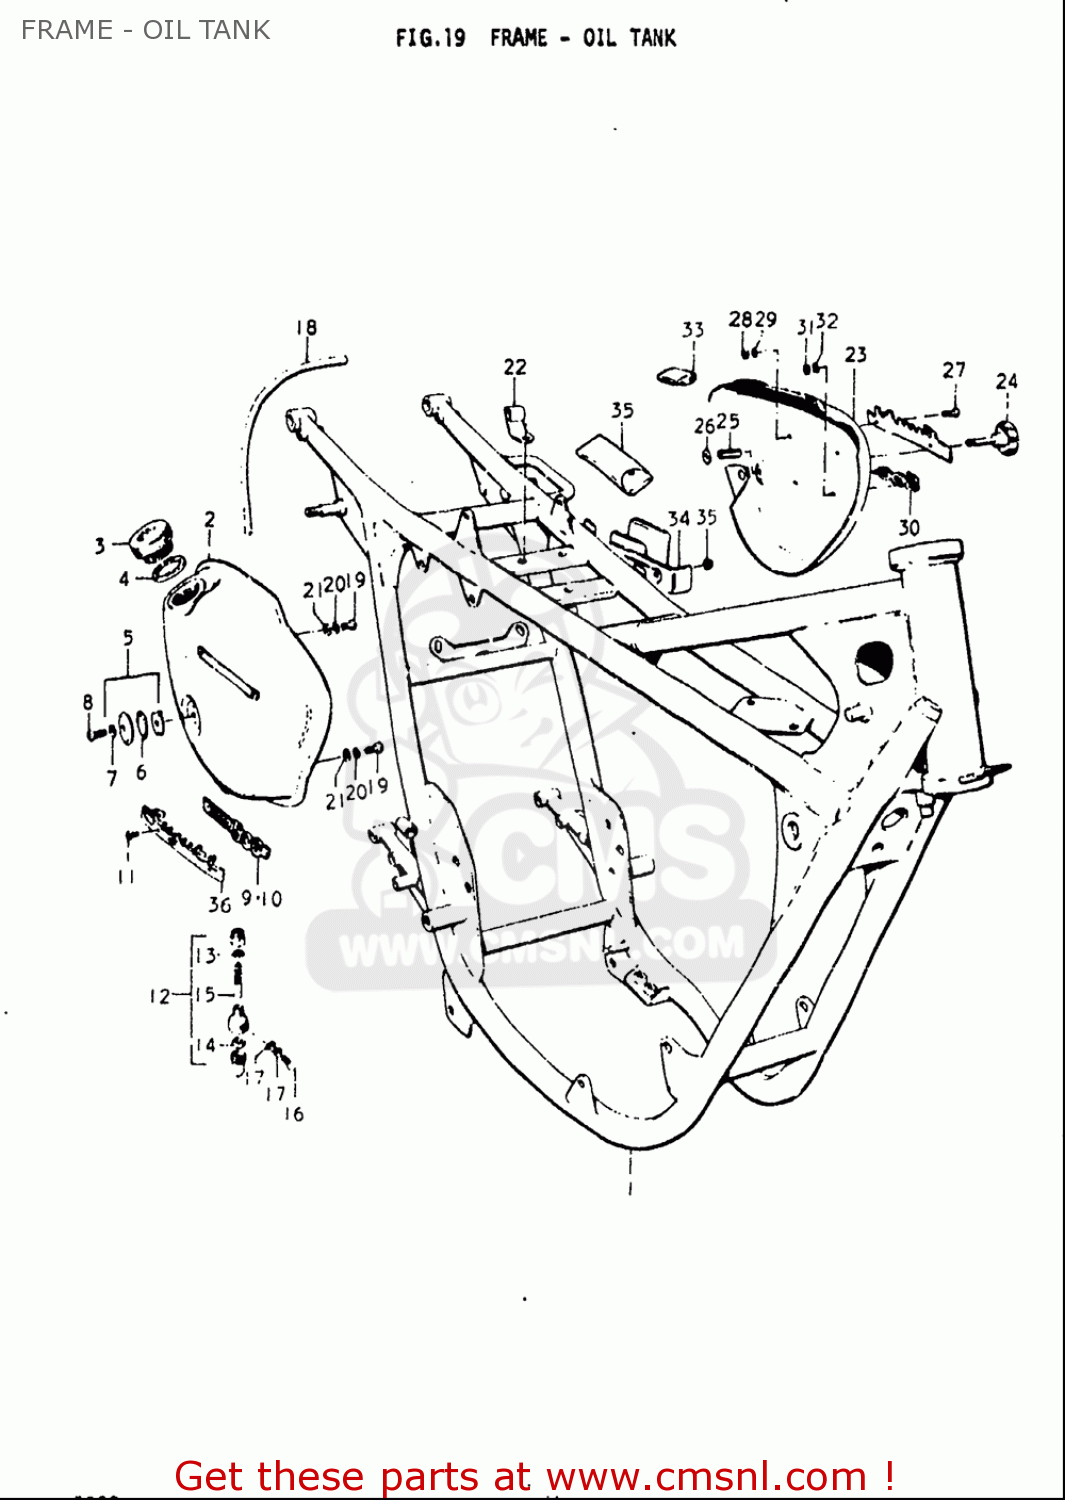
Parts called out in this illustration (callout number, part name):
3	CAP,OIL TANK
4	GASKET,OIL TANK FILLER CAP (NAS)
5	LENS SET,OIL INSPECTION
6	O RING(D:3,ID:23)
7	GASKET(5X9.5X1) (NAS)
8	SCREW
11	SCREW
13	GASKET,OIL OUTLET JOINT (NAS)
14	GASKET,STRAINER CUP (NAS)
15	UNIT,OIL FILTER
16	UNION BOLT
17	GASKET(6.2X11X1).2 (NAS)
18	HOSE(5X8X2000)
19	BOLT
20	WASHER,LOCK
21	WASHER
26	NUT
27	SCREW
28	NUT
29	WASHER,LOCK
31	NUT
32	WASHER,LOCK
35	NUT
